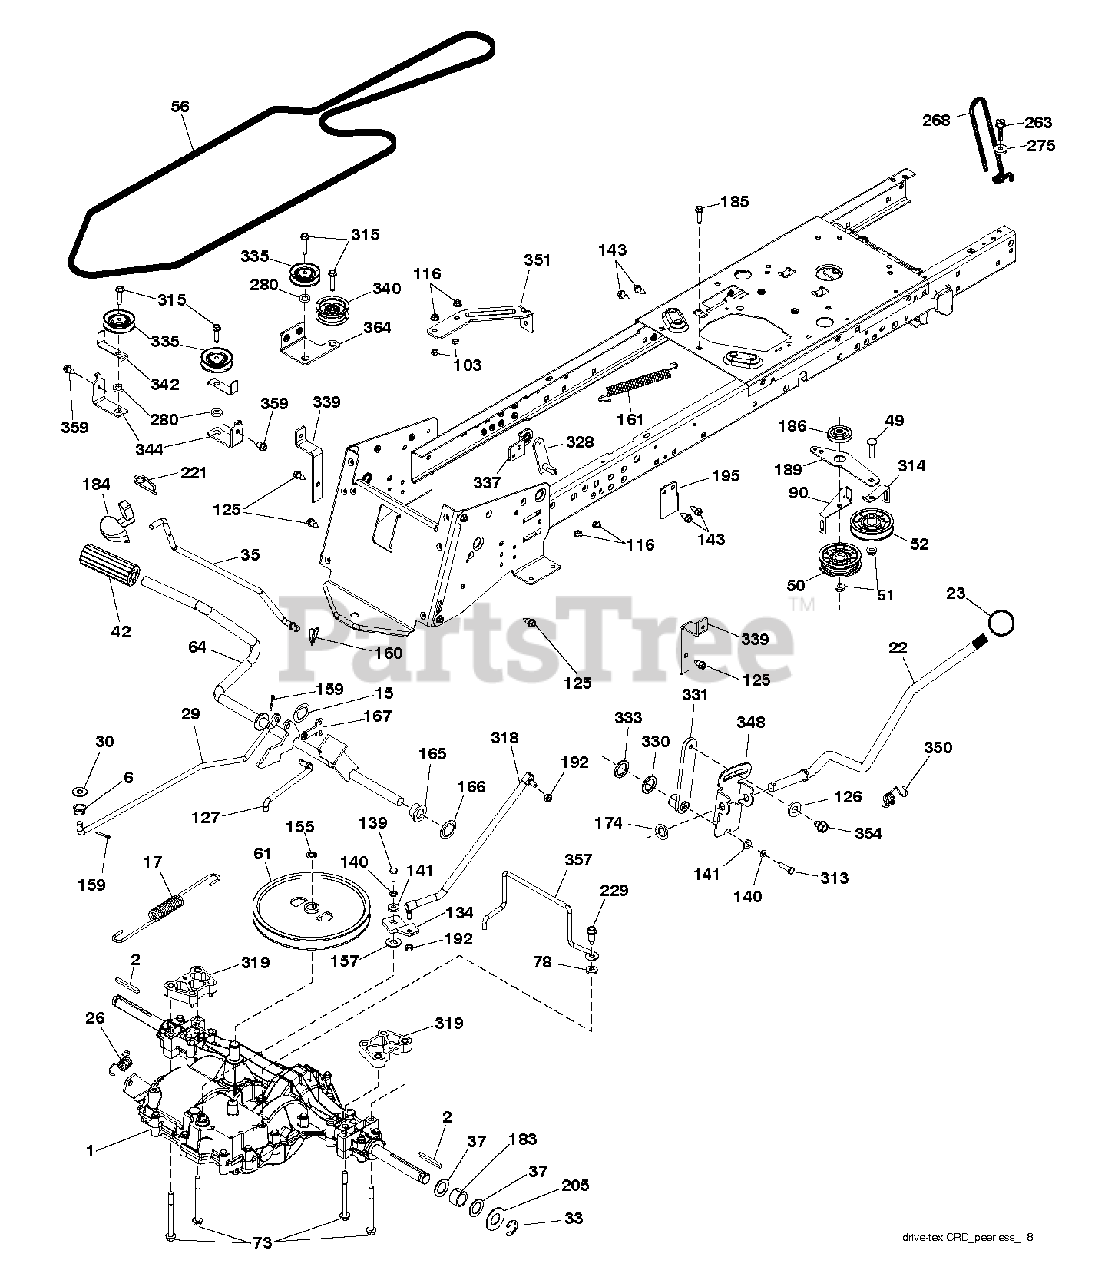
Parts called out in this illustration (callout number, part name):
2	SQUARE KEY
6	BUSHING.SNAP.NYL.BLK.
15	WASHER
17	SPRING SPRING BRAKE GEAR CRD
22	ROD ROD SHIFT FENDER
23	KNOB.DUCKHEAD.1/2
26	SPRING,BRAKE RETURN
29	ROD.BRAKE.GEAR.CRD.TEX
30	WASHER
35	ROD.CNTRL.PARK.PREDATOR.LT.TEX
37	WASHER.HARDENED
42	PEDAL COVER T
50	IDLER.FLAT.910.OFFSET
51	NUT LOCK FLG 3/8-16 UNC
52	IDLER.V-GROOVE.910.OFFSET
56	BELT BELT V CRD GEAR
61	PULLEY
64	SHAFT.ASM.PEDAL.BRAKE.
73	BOLT.FLANGED
90	KEEPER KEEPER BELT CLUTCHING T
103	JAM NUT TI
116	NUT LOCK HEX FLANGE 5/16-18
125	SCREW
126	WASHER.SRRTD.5/16
127	RP LINK.CLUTCH.GROUND.DRIVE
139	BOLT 1/4-28X3/4
140	LOCKWASHER
141	WASHER LT
143	SCREW LT
155	RETAINING RING LT
157	WASH-SHFT PLT LT
159	COTTER PIN
160	RETAINER CLIP
161	SPRING, RETURN LT
165	BUSHING.SHAFT.BRAKE.HAND
166	NUT.PUSH.625
167	LATCH.BRAKE.SPRING
174	NUT.PUSH.500.2006
183	SPACER AXLE
184	HANDLE.PARKNG BRK.PRED.LT.428
186	SPACER.RETAINER
189	BELLCRANK BELLCRANK GROUNDDRI
192	NUT LOCK CENTER 1/4 -28 FNTHD
195	BRACKET.ROD.BRAKE
221	RETAINER.SPRING.CLIP.H
229	SCREW 5/16-18X1
263	SCREW, 3/8-16X3/4
268	GUARD MUFFLER
275	WASHER
280	WASHER T
313	BOLT
314	RETAINER KEEPER BELT
315	BOLT.5/16-18X1.25
318	GEAR LINK SHIFT GEAR
319	SPACER SPACER TRANSAXLE TEX C
328	SHAFT SHAFT SHIFT FRONT
330	PULLEY.V-IDLER.
331	HUB HUB SHIFT FENDER
333	WASHER.WAVE.SPRING
335	PULLEY.V-IDLER.
337	BRACKET BRACKET SUPT SHIFT CR
339	STRAP STRAP TORQUE K46 CRD TE
340	IDLER.FLAT.2.25.INCH
342	BELT GUIDE
344	BRACKET BRACKET IDLER CRD TEX
348	ARM ARM CLEVIS ROD SHIFT TEX C
350	TORSION SPRING SPRING TORSION
351	BRACKET BRACKET DECK SWAY
354	CAPSCREW.HXHD.FLG.5/16-18X.625
357	KEEPER KEEPER
359	SCREW LT.3/8-46X5/8
364	BRACKET BRACKET IDLER CRD TEX
